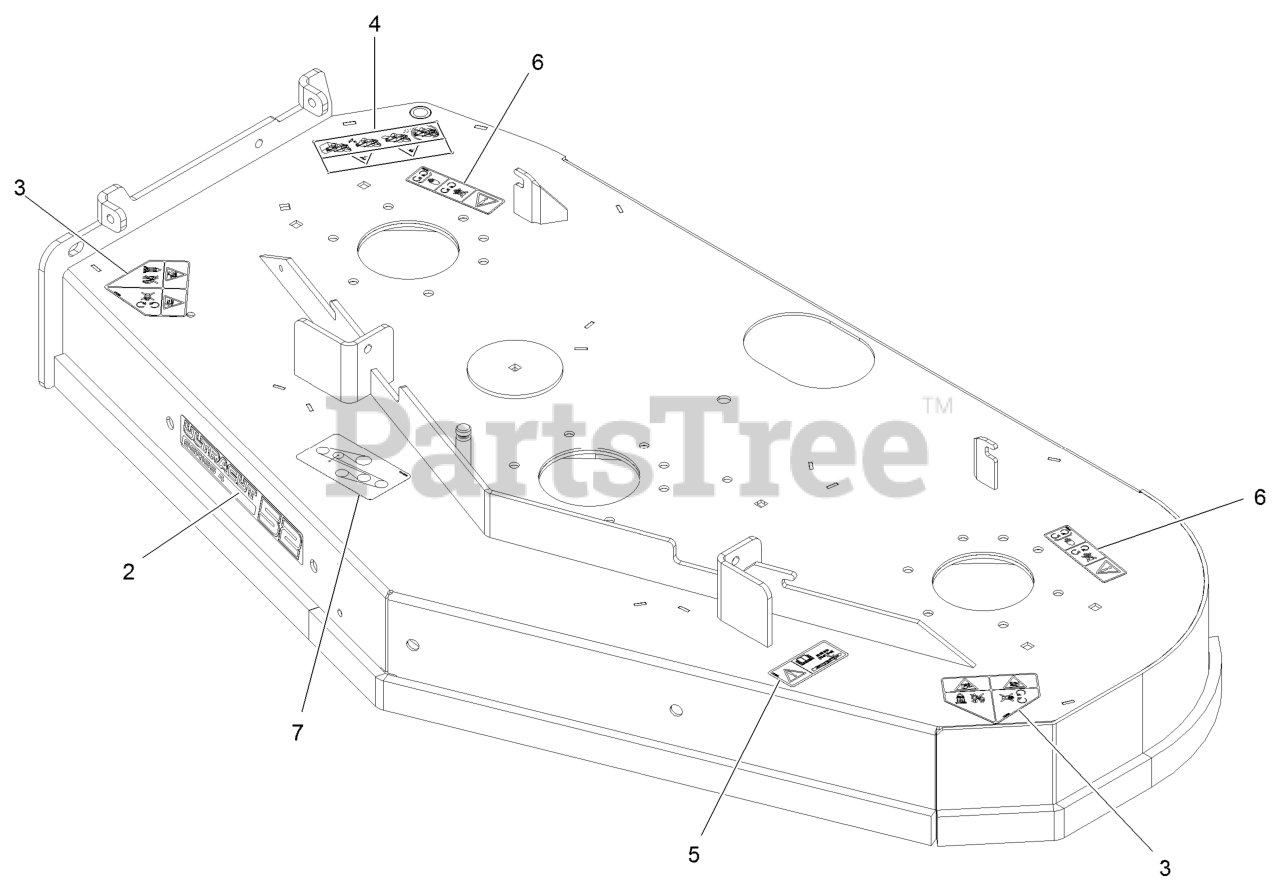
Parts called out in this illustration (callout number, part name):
2	Decal, 524
3	Decal-Danger
4	Decal-Warning, Bagger
5	Decal-Bolt Torque
6	Decal-Missing, Cover
7	Decal-Belt Routing
